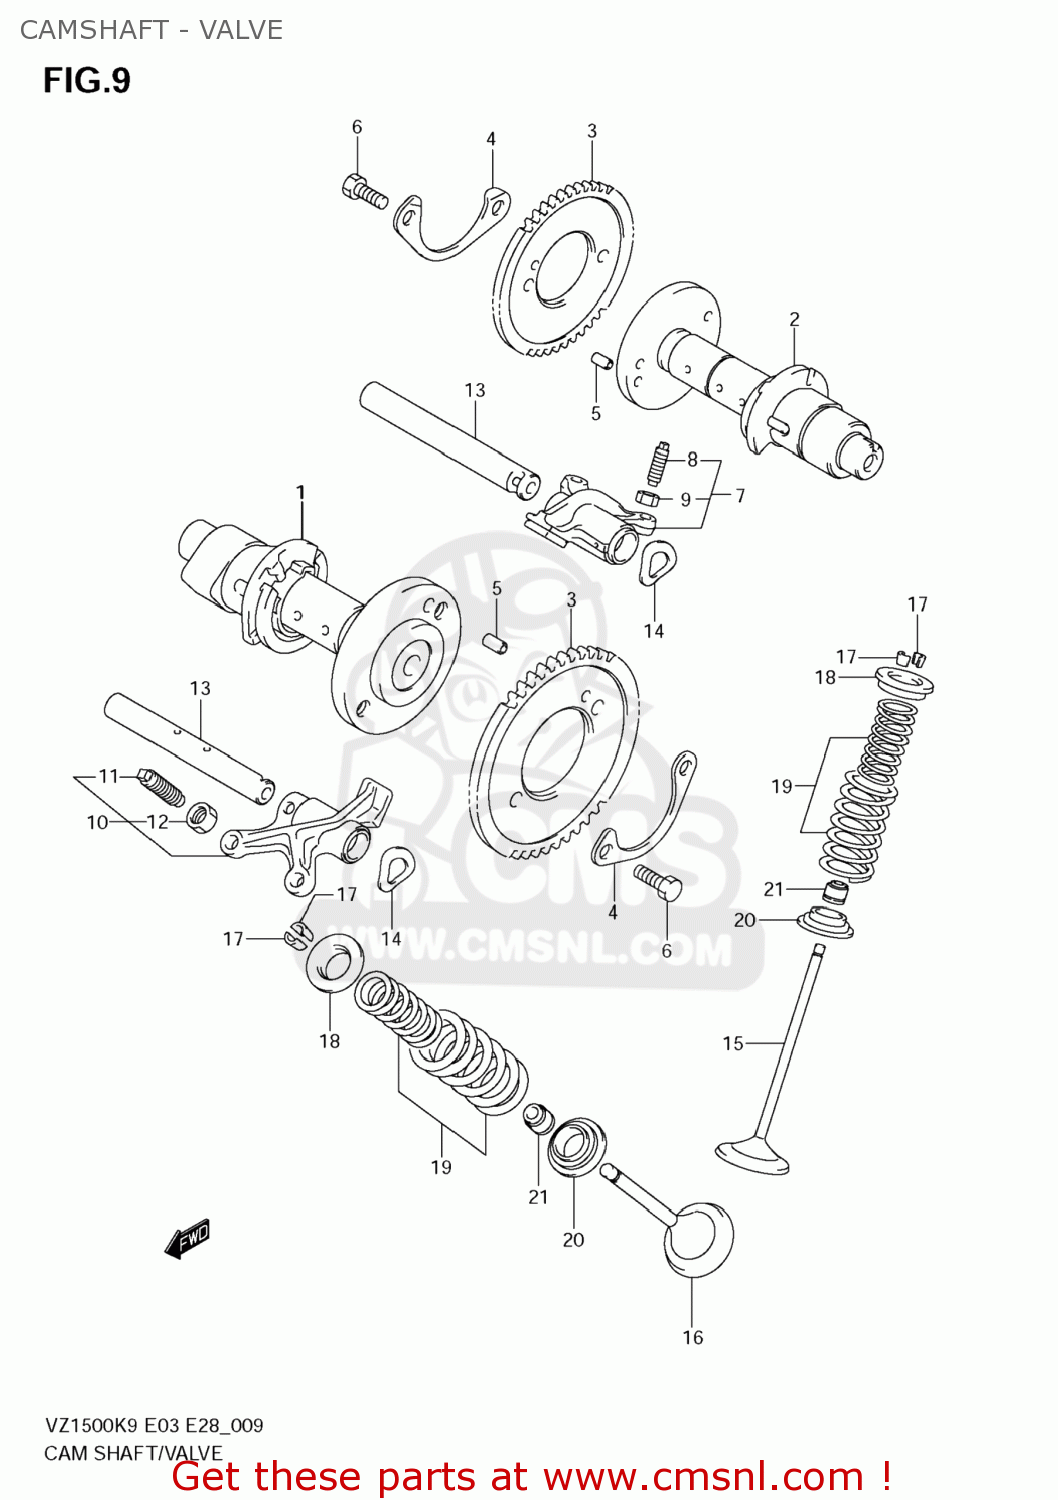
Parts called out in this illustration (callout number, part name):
1	CAMSHAFT,FR
2	CAMSHAFT,RR
3	SPROCKET,CAMSHAFT
4	WASHER,SPROCKET
5	PIN
6	BOLT(6X12.5)
7	ARM,VALVE ROCKER INTAKE
8	SCREW,TAPPET ADJUSTING
9	NUT,ADJUSTING SCREW
10	ARM,VALVE ROCKER EXHAUST
11	SCREW,TAPPET ADJUSTING
12	NUT,ADJUSTING SCREW
13	SHAFT,VALVE ROCKER ARM
14	WASHER
15	VALVE,INTAKE
16	VALVE,EXHAUST
17	COTTER,VALVE
18	RETAINER,VALVE SPRING
19	SPRING SET,VALVE
20	SEAT,VALVE SPRING
21	SEAL,OIL(5.5X11X8.2)
